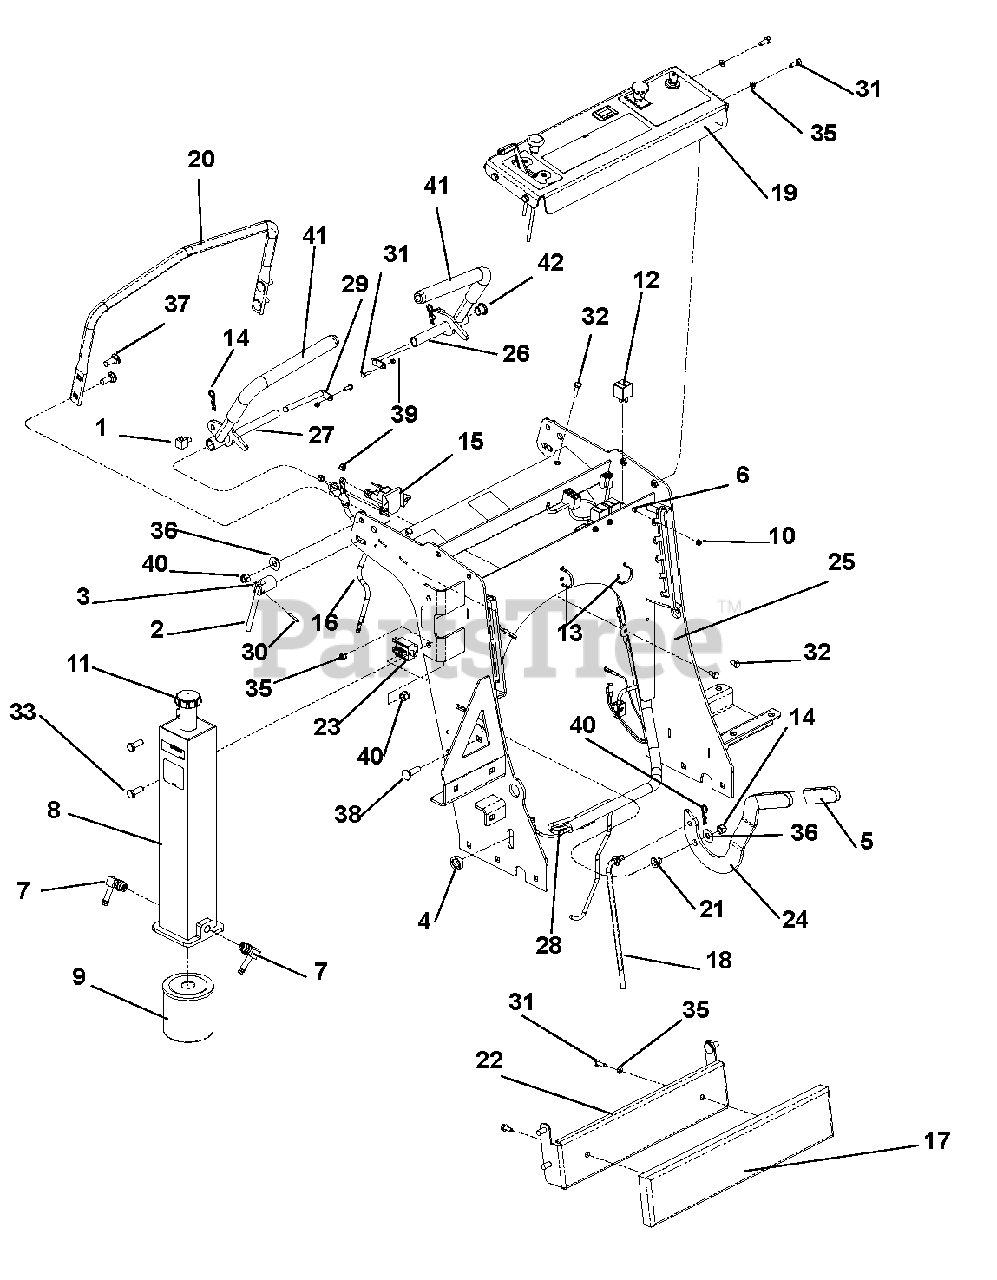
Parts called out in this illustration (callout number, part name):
1	Swivel Adjuster
2	Lever, Lock Y
3	Base, Lock Lever Y
4	Grommet, Rubber .88 ID x 1.38 OD x .14
5	Grip, PVC .250 x 1.00 x 3.63
6	Screw, 8-32 x .50 Y
7	Fitting, 90 9/16 MOR x 3/8 Hose
8	Weldment, Reservior Hydraulic w/Decal
9	Filter, Oil
10	Nut, 8-32 Elastic Stop
11	Cap, Filler Oil
12	Relay, Iso Mini Elec.
13	Cable Tie, .15 x 8.50
14	Pin, Hair .091 x 1.63
15	Solenoid, 12 V Starter
16	Cable, 12" Starter
17	Pad, Thigh
18	Link, Brake
19	Assembly, Control Panel w/Decals
20	Handle, Support
21	Bushing, Brake Pivot Y
22	Weldment, Thigh Pad Bracket
23	Switch, NO-NO-NC Grey Plunger
24	Brake Lever, Offset
25	Weldment, Console 34 w/Decals
26	RH Control Lever w/Grip
27	LH Control Lever w/Grip
28	Harness, Wiring
29	Weldment, Pin and Lock
30	Pin, Spring 5/32 x 1
31	Bolt, Hex .25-20 x .75 Grade 5
32	Bolt, .25-20 x 1.00 Hex 5 Y
33	Bolt, Hex .38-16 x 1.00 Grade 5
34	Nut, .25-20 Standard Hex Grade 5 Y
35	Washer, .250 Med Spring Lock
36	Washer, .375 Reg Flat
37	Bolt, Round Head Square Neck .38-16 x 1.00 Grade 5
38	Bolt, Round Head Square Neck .38-16 x 1.25 Grade 5
39	Nut, Locking-Nylon .250-20
40	Nut, Locking-Nylon .38-16
41	Grip, Control
42	Bearing, Flange .500 x .625 x .500 Bronze
